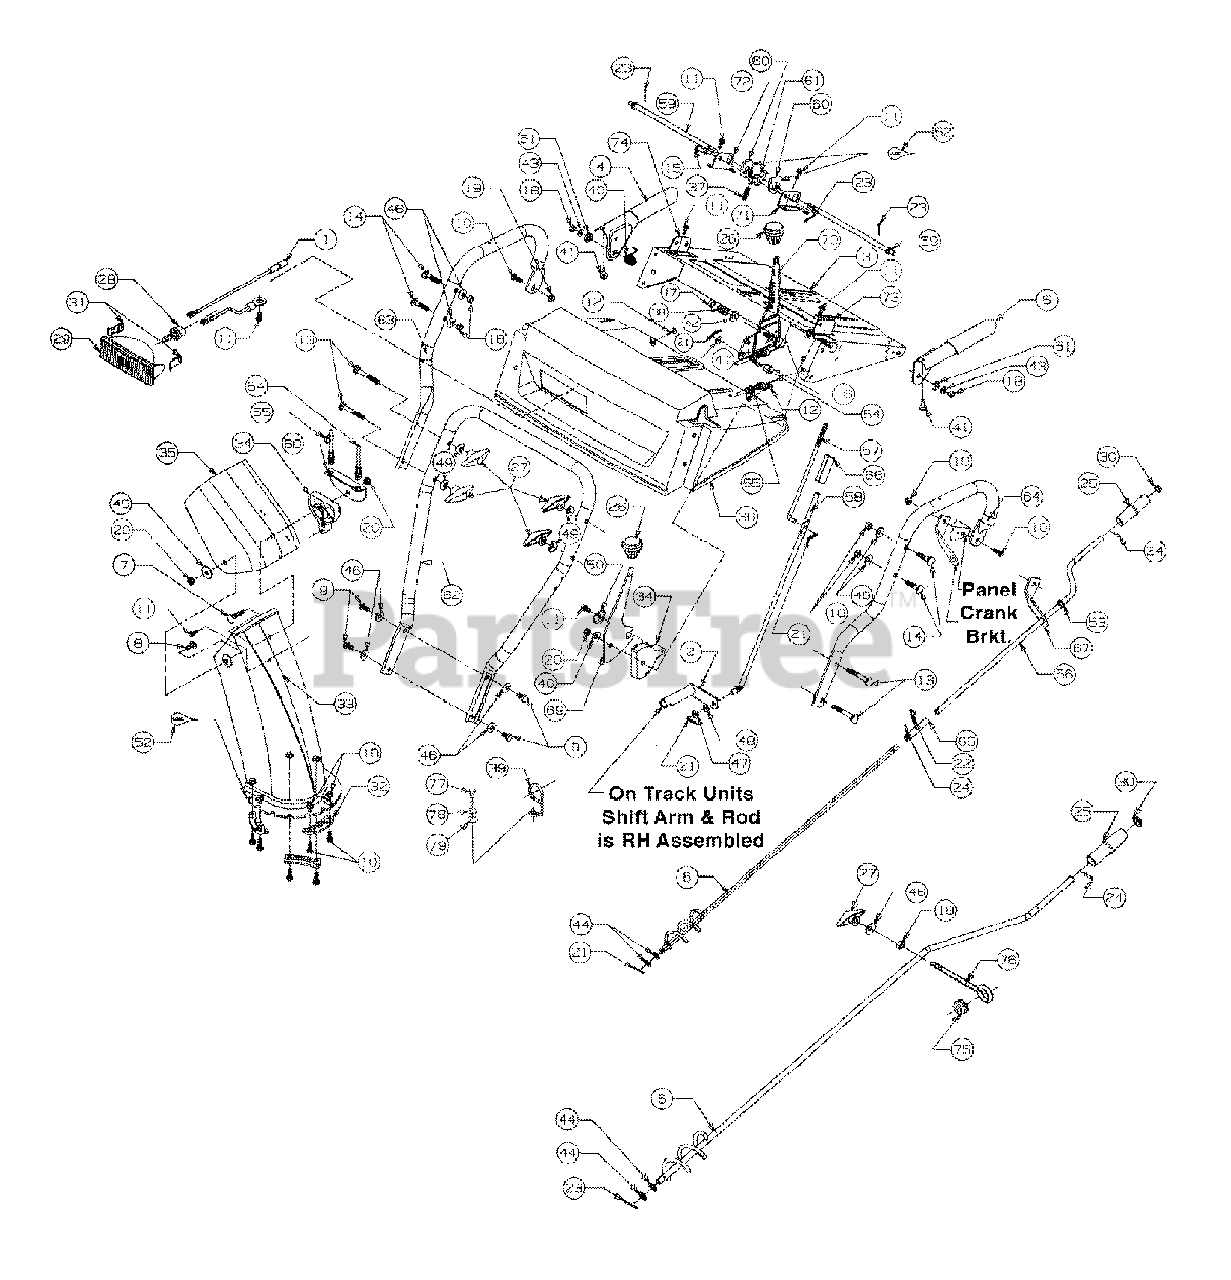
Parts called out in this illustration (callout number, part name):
1	Harness-Light
2	Arm-Shift
5	Handle-Engagement - L.H.
6	Crank-Chute (623)
6	Crank-Chute
7	Bolt-Carriage
8	Bolt-Carriage
9	Screw-Hex
10	Screw-Hex
11	Screw-Washer Head-Hex
12	Screw-Hex
13	Bolt-Carriage
14	Bolt-Carriage
15	Pin-Clevis
16	Ferrule
17	Nut-Hex Lock
18	Nut-Hex
19	Nut-Hex Lock
20	Nut-Hex Lock
21	Pin-Cotter Internal
22	Pin-Cotter
23	Pin-Cotter
24	Pin-Roll
25	Knob-Chute Crank
26	Knob-Shift
27	Knob-Wing Nut
29	Housing-Lamp
30	Cap-Push
31	Clip-Retaining
32	Keeper-Chute
33	Chute-Lower
34	Guide-Cable
35	Chute-Upper
36	Panel-Handle
37	Spring
38	Spring
39	Wire-Control
40	Spring
41	Bumper
42	Washer-Bell
43	Washer-Lock
44	Washer-Flat
45	Washer
46	Washer-Bell
47	Washer-Flat
48	Washer-Lock
49	Washer-Saddle
50	Washer
51	Washer
52	Lubricant
53	Bushing-Plastic
54	Cable-Chute Control
55	Cable-Chute Control
56	Crank-Chute
57	Rod-Shift Upper
58	Rod-Shift Lower
59	Rod-Cam
60	Cam-Handle Lock
61	Pawl-Handle Lock
62	Handle-Lower
63	Handle - R.H.
64	Handle - L.H.
65	Spacer
66	Connector
67	Bracket
69	Handle-Chute Tilt
70	Handle-Shift
71	Bracket-Handle Support - L.H.
72	Bracket-Handle Support - R.H.
74	Bracket-Handle Support - R.H.
75	Grommet-Rubber
76	Eyebolt-Chute
77	Screw-Washer Head-Hex
78	Washer-Lock
79	Washer-Flat
